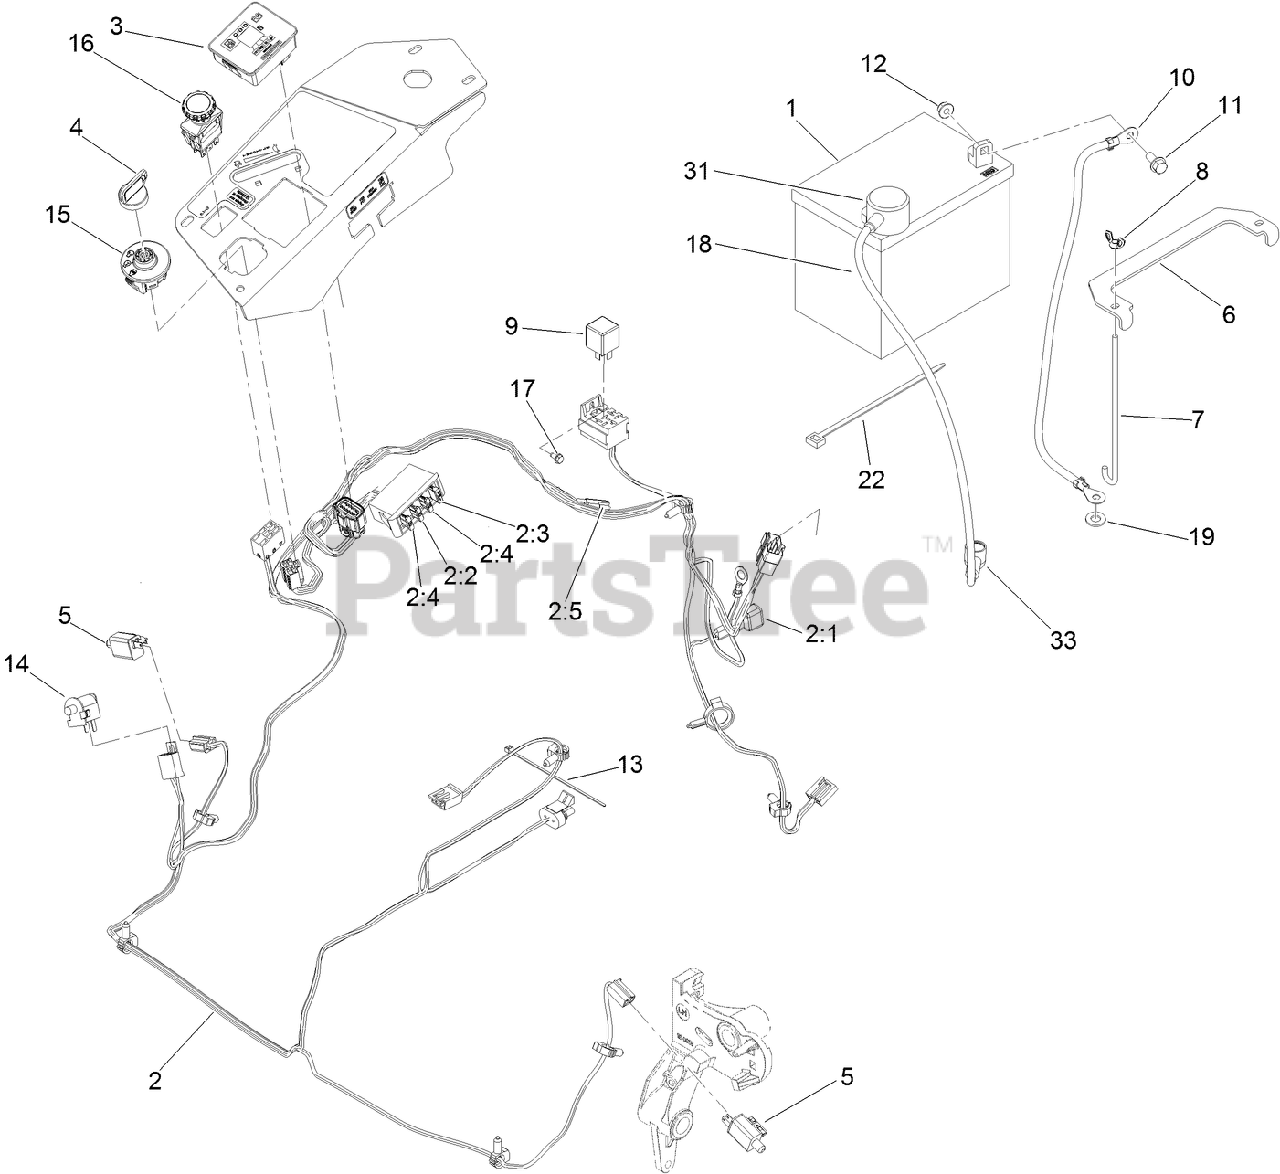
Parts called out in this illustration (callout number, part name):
1	BATTERY-DRY
2	HARNESS-WIRE, MAIN
2:2	FUSE-BLADE, 10 AMP
2:3	FUSE-BLADE, 15 AMP
2:4	FUSE-BLADE, 25 AMP
2:5	CAP-PLUG
3	FUEL/HOUR METER ASM
4	KEY-IGNITION
5	SWITCH
6	STRAP-TIE DOWN, BATTERY
7	BOLT-HOLDDOWN
8	WINGNUT
10	CABLE-BATTERY, NEGATIVE
11	SCREW-HHF
12	NUT-HF, NI
13	TIE-CABLE
14	SWITCH-BAIL
15	SWITCH-IGNITION
16	SWITCH-PTO, 10 AMP
17	SCREW-HWH
18	CABLE-BATTERY, POSITIVE
19	WASHER-FLAT
22	TIE-PLASTIC
31	INSULATOR-BATTERY
33	INSULATOR-SOLENOID
